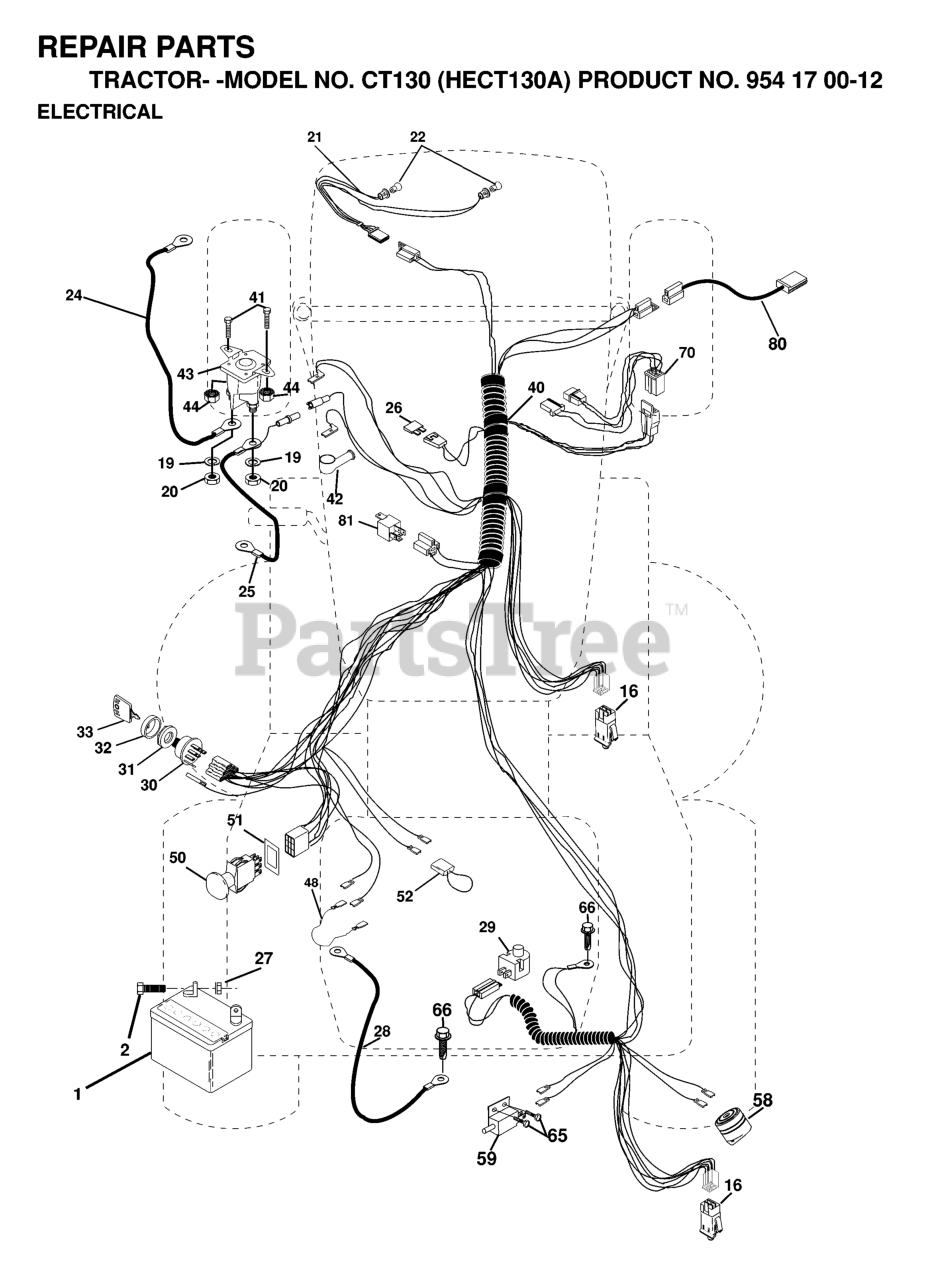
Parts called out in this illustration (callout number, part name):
1	BATTERY 12 VOLT 25 AMP
2	BOLT.HEX.1/4.X.3/4.DICHROMATE
16	SWITCH INTERLOCK
19	LOCKWASHER
20	NUT
24	BATTERY CABLE GT
25	CABLE BATTERY
26	FUSE 15 AMP
27	NUT
28	CABLE GROUND
29	PLUNGER SWITCH (COLOR:OLIVE)
30	SWITCH.IGNITION.4.POSITION
31	NUT IGNITION
32	COVER SWITCH KEY
33	KEY.MOLDED.GENERIC
40	CABLE ASS[
41	BOLT
42	TERMINAL COVER
43	SOLINOID
44	Nut, Keps Blk Hex 1/4-20 UNC
48	ADAPTER.AMMETER
50	SWITCH PTO 3 PDT
51	FRAME RETAINING RING
52	WIRE PROTECTION LOOP
58	REPL BY 532 16 59-93
65	Screw, Hex Wsh. Tap #10-16 x 1/2
70	CABLE ASS[
80	HARNESS, CLUTCH
81	RELAY.ASSY.T
